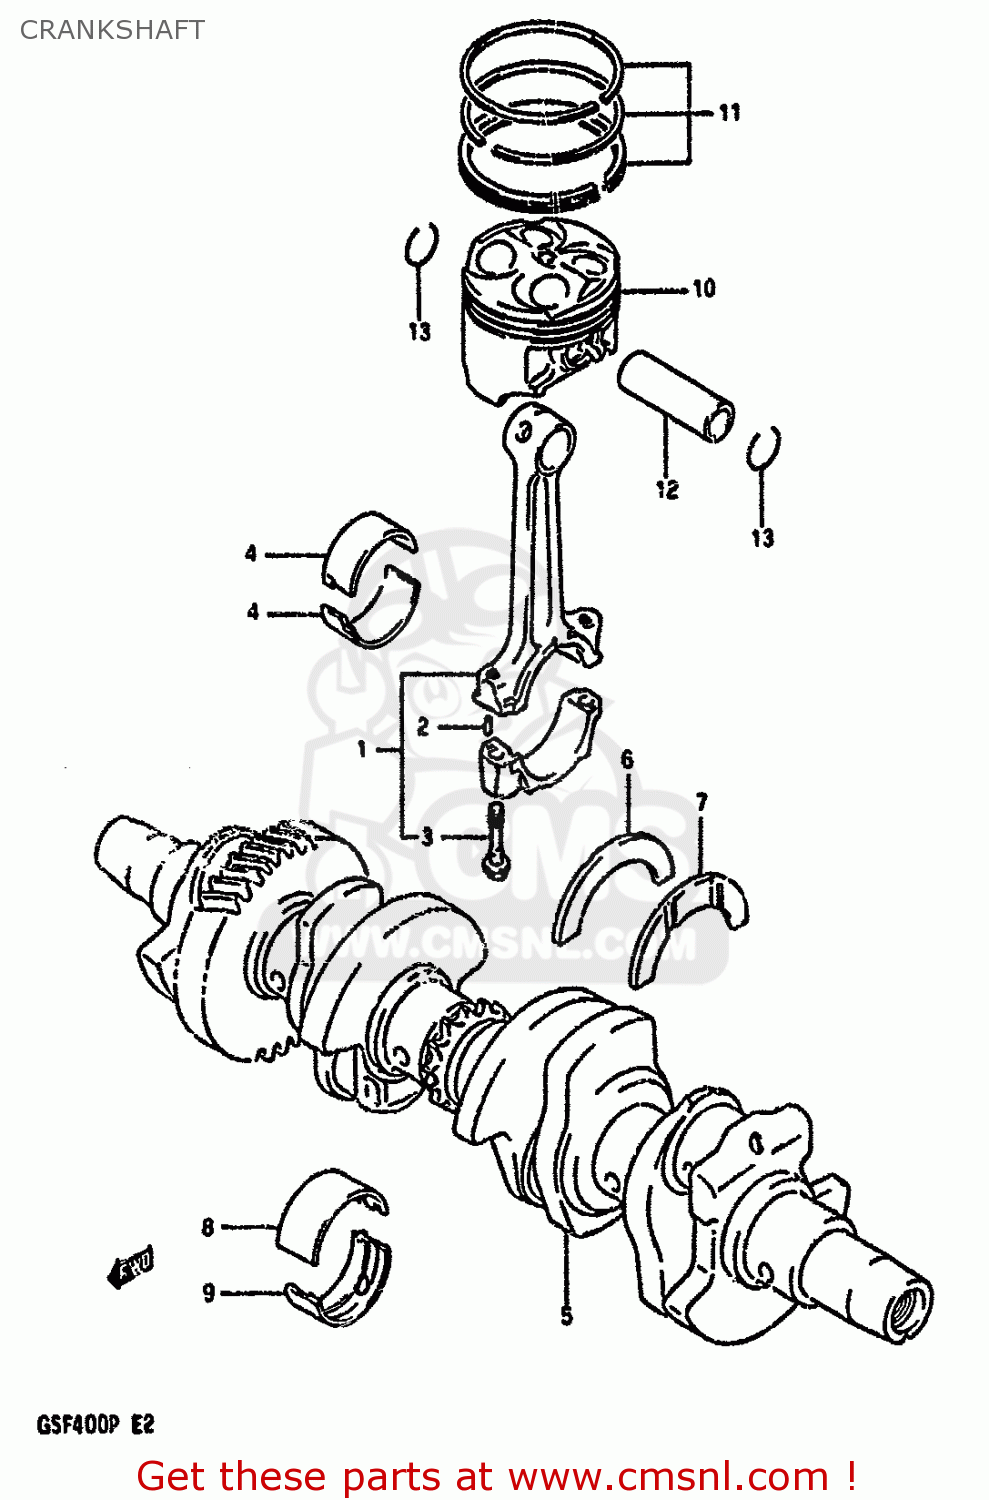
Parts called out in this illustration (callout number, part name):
1	CONNECTING ROD ASSY
2	PIN 3X5
3	BOLT,CONNECTING ROD
4	BEARING,CRANK PIN
5	CRANKSHAFT SET
6	PLATE,CRANK THRUST
7	PLATE,CRANK THRUST
8	BEARING,CRANKSHAFT UPR
9	BEARING,CRANKSHAFT(GREEN)
10	PISTON
11	RING SET,PISTON
12	PIN,PISTON
13	RING,SNAP 16MM
